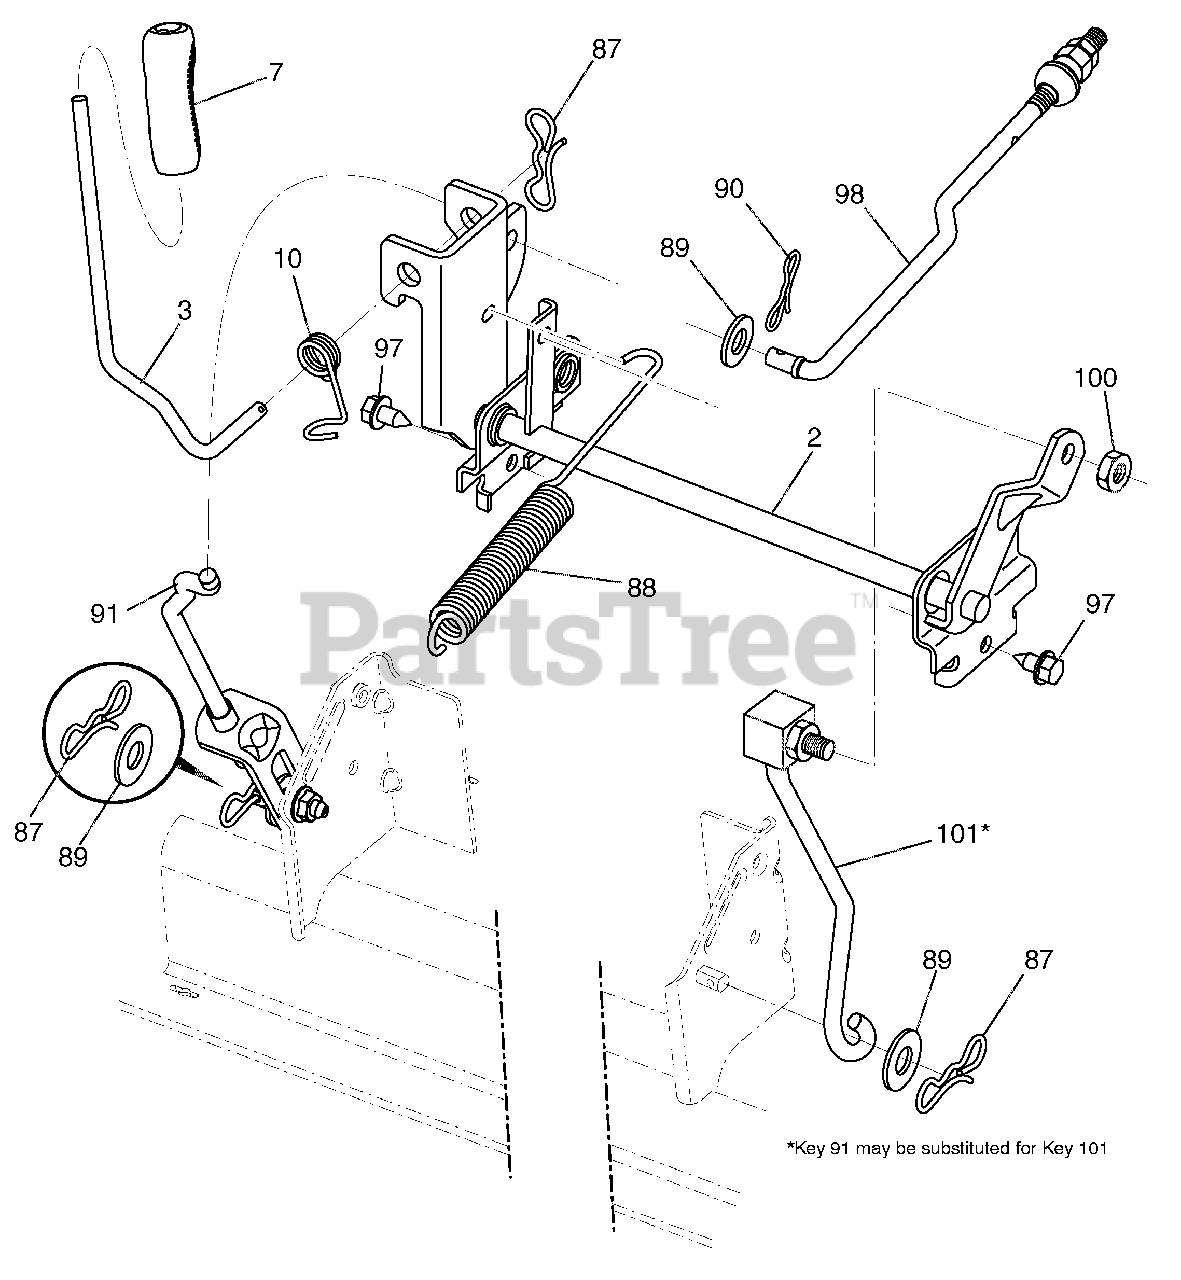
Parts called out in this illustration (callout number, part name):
2	SHAFT ASM., LIFT
3	LEVER.LIFT.HANDLE.LT
7	GRIP LEVER 5625 LD BLACK 428
10	SPRING.TORSION.HANDLE.LIFT
87	PIN.COTTER.7/16.BOW TIE LOCK
88	SPRING.LIFT ASSIST
89	WASHER.CLEAR ZINC
90	PIN.COTTER.5/16.BOW TIE LOCK
91	LINK ASM.LIFT.LH.REAR
97	SCREW.HEXWSH THDR3/8-16X3/4.BL
98	LINK ASM.SUSP.FRONT.MWR.11
100	NUT.CENTERLOCK.3/8-16 UNC.
101	LINK ASM.LIFT.FIXED.38/42/46"
